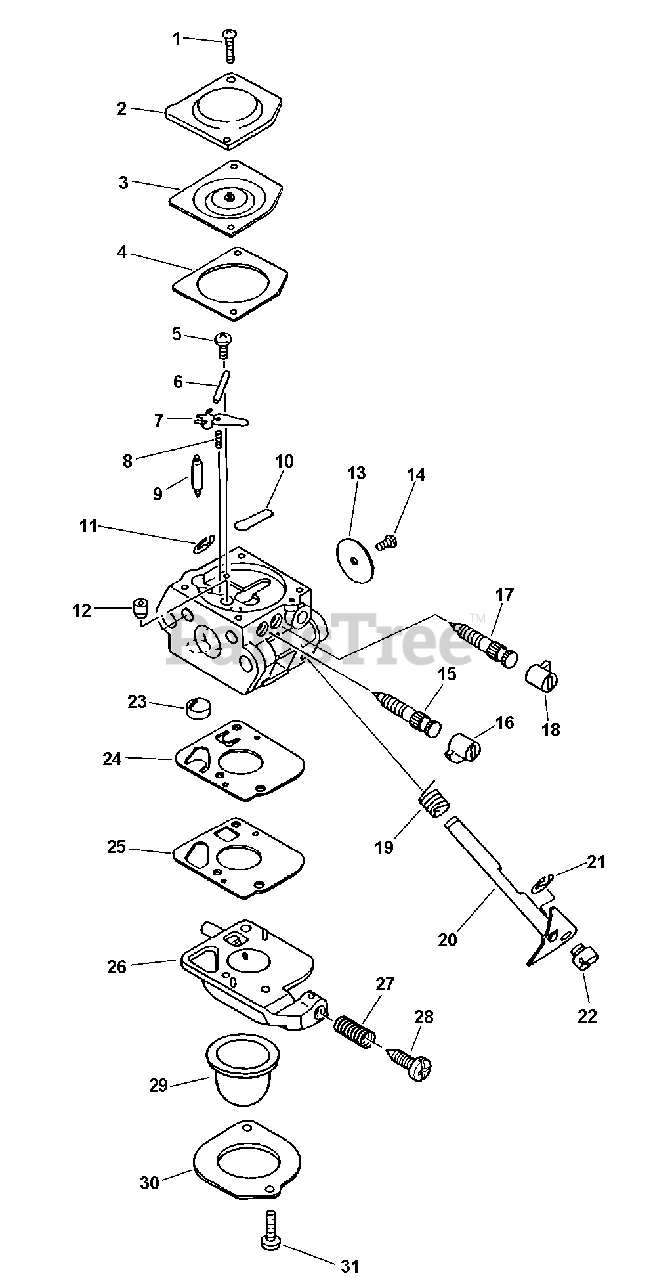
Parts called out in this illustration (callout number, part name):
2	COVER, METERING DIAPHRAGM
3	REPAIR KIT, CARBURETOR
3	GASKET / DIAPHRAGM KIT
4	REPAIR KIT, CARBURETOR
4	GASKET / DIAPHRAGM KIT
6	REPAIR KIT, CARBURETOR
7	REPAIR KIT, CARBURETOR
8	REPAIR KIT, CARBURETOR
9	REPAIR KIT, CARBURETOR
10	REPAIR KIT, CARBURETOR
12	NOZZLE, CHECK VALVE
13	VALVE, THROTTLE
15	NEEDLE, HIGH SPEED
16	CAP, LIMITER - RED
17	NEEDLE, LOW SPEED
18	CAP, LIMITER - WHITE
19	SPRING, THROTTLE RETURN
20	SHAFT, THROTTLE
23	REPAIR KIT, CARBURETOR
24	REPAIR KIT, CARBURETOR
24	GASKET / DIAPHRAGM KIT
25	REPAIR KIT, CARBURETOR
25	GASKET / DIAPHRAGM KIT
26	BODY ASSY, PURGE
28	SCREW, THROTTLE ADJUST
29	BULB, PURGE
30	RETAINER
